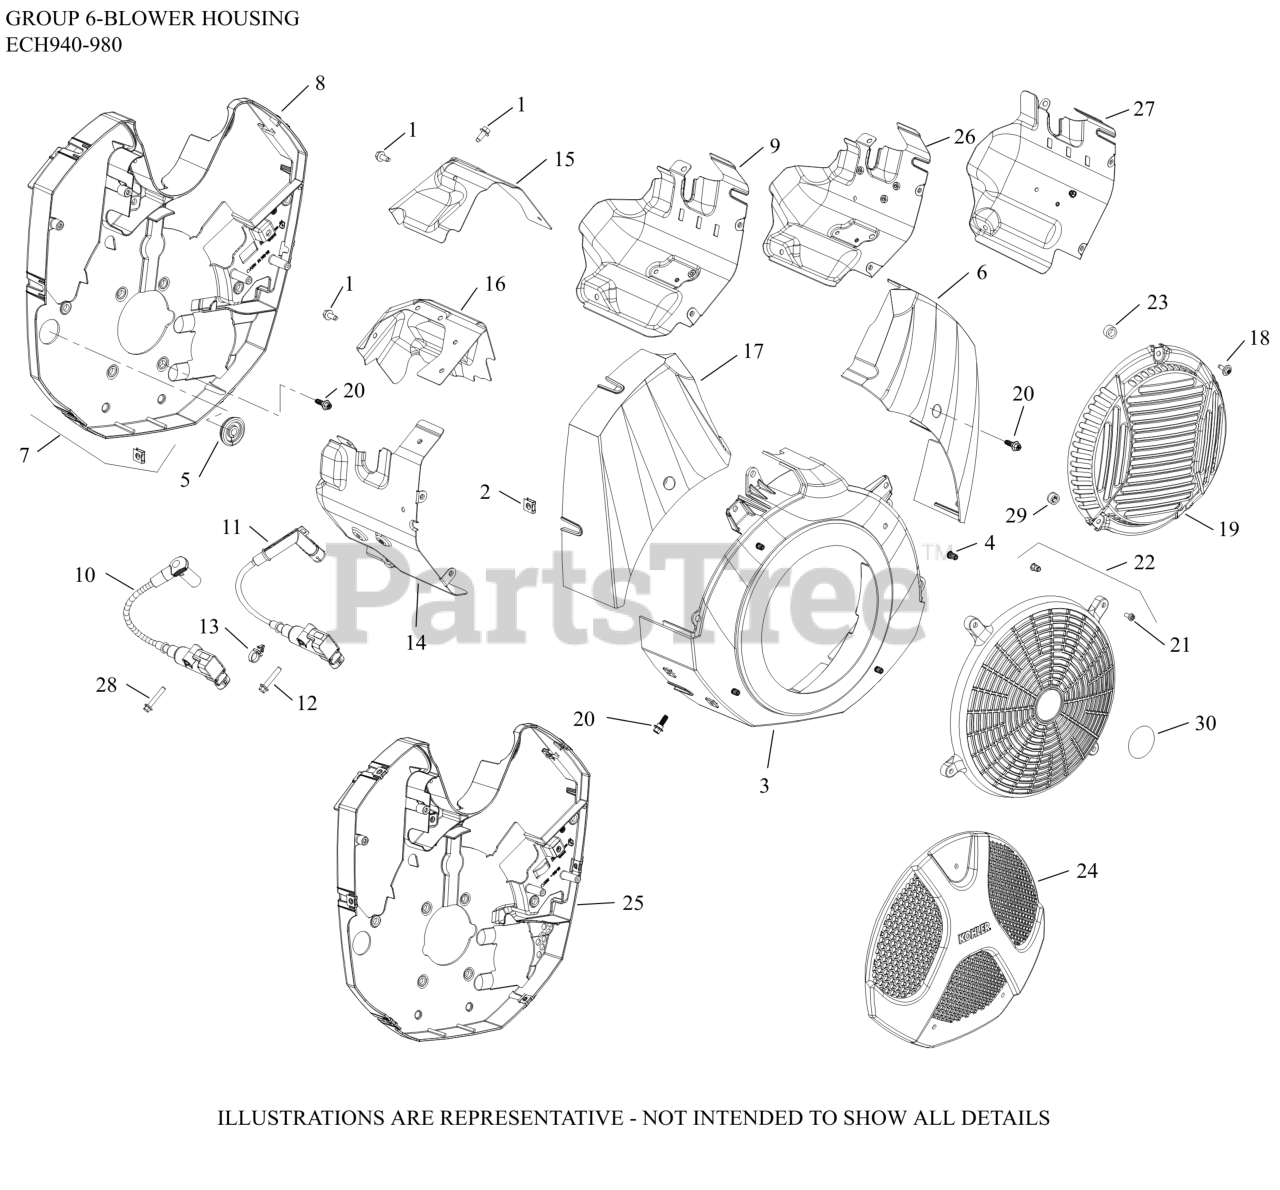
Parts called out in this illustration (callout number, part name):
1	SCREW, THREAD FORMING
2	CLIP, BAFFLE MOUNTING
3	KIT, BLOWER HOUSING
4	INSERT, THREADED (M5)
5	CGROMMET, WIRING HARNESS
6	SHROUD, #1 CYLINDER
9	BAFFLE, BARREL (#1 CYL)
11	COIL, IGNITION - EFI (RFI/EMC)
14	BAFFLE, BARREL (#2 CYL)
15	BAFFLE, VALLEY #1 CYLINDER
16	BAFFLE, VALLEY #2 CYL-USE 62 063 40-S
17	SHROUD, #2 CYLINDER
18	SCREW, SEMS
19	GUARD, GRASS SCREEN (METAL)
20	SCREW, SHD THD FRM
25	SHROUD AND CLIP ASSEMBLY
28	SCREW, HEX FLANGE
